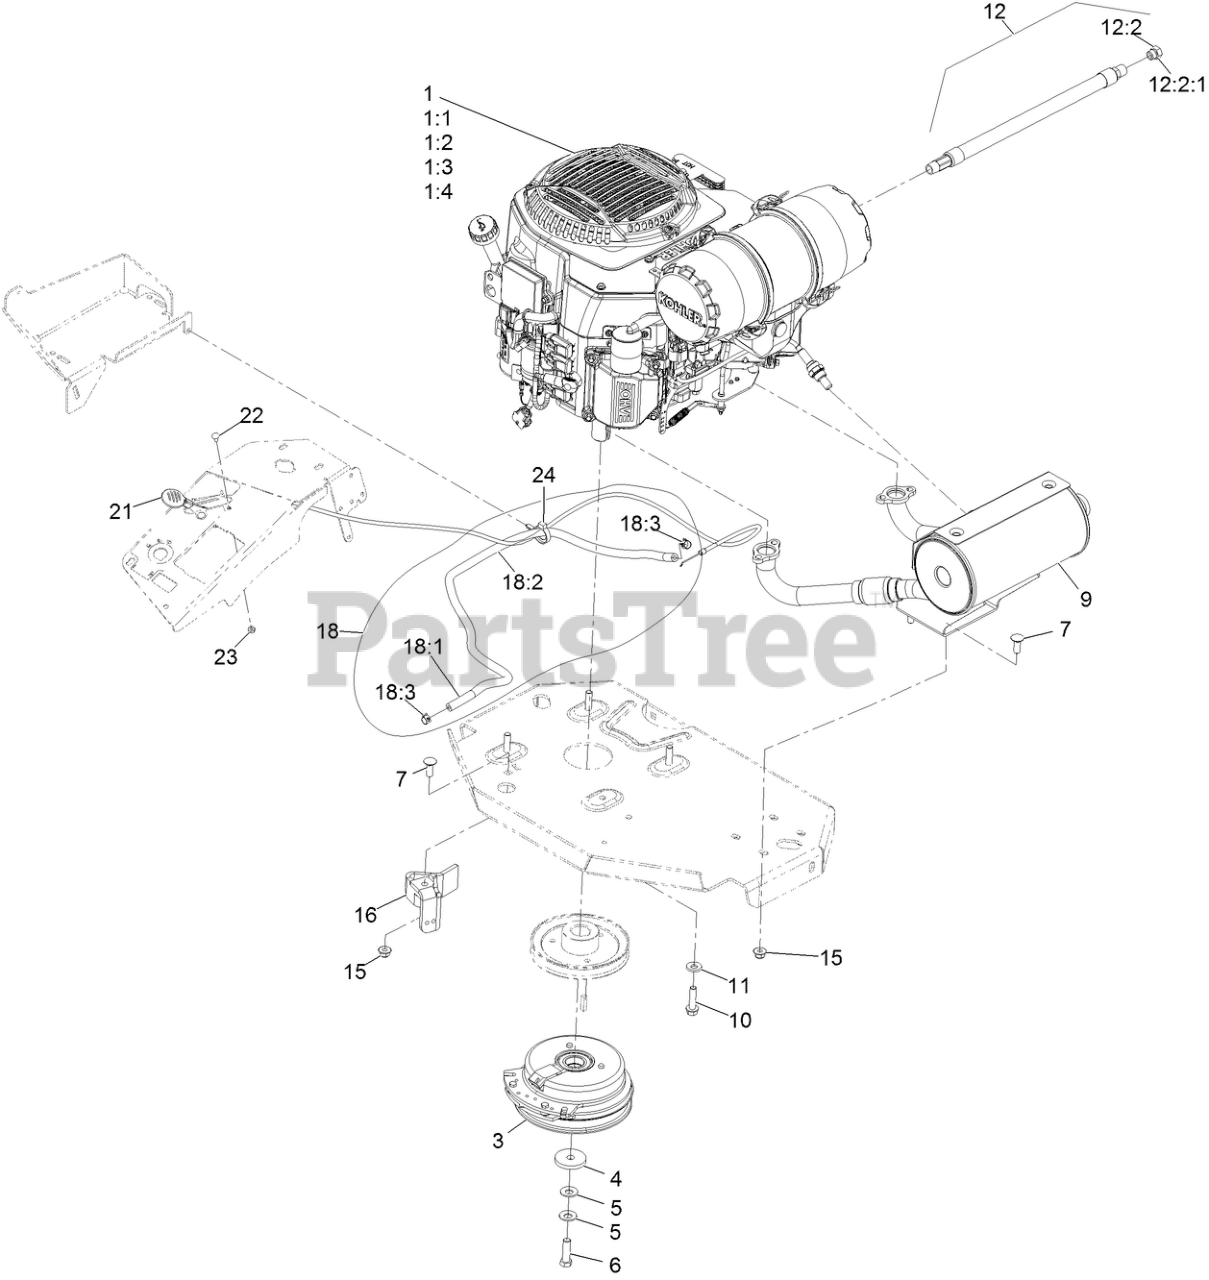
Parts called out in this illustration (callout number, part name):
1:1	Kohler 52 050 02-S Engine Oil Filter
1:2	Kohler 25 083 01-S Engine Air Filter
1:3	Kohler 25 083 04-S Safety Filter
1:4	Kohler 25 050 42-S Fuel Filter
3	CLUTCH KIT
4	WASHER-CLUTCH
5	WASHER-SPRING
6	SCREW-HH 7/16-20 X 1 1/2 W/LOCTITE
7	SCREW-CARR
9	KIT,MUFFLER
10	SCREW-HWH
11	WASHER-BELLEVILLE
12	OIL DRAIN HOSE ASM
12:2	PLUG-HH
12:2:1	O-RING
15	NUT-HF, NI
16	CLUTCH-ANCHOR
18	FUEL LINE ASM
18:1	HOSE-FUEL
18:2	SLEEVE-THERMAL
18:3	CLAMP-HOSE
21	ASM,THROTTLE CABLE
22	BOLT-CARR
23	NUT-LOCK, NI
24	CLAMP-HOSE
